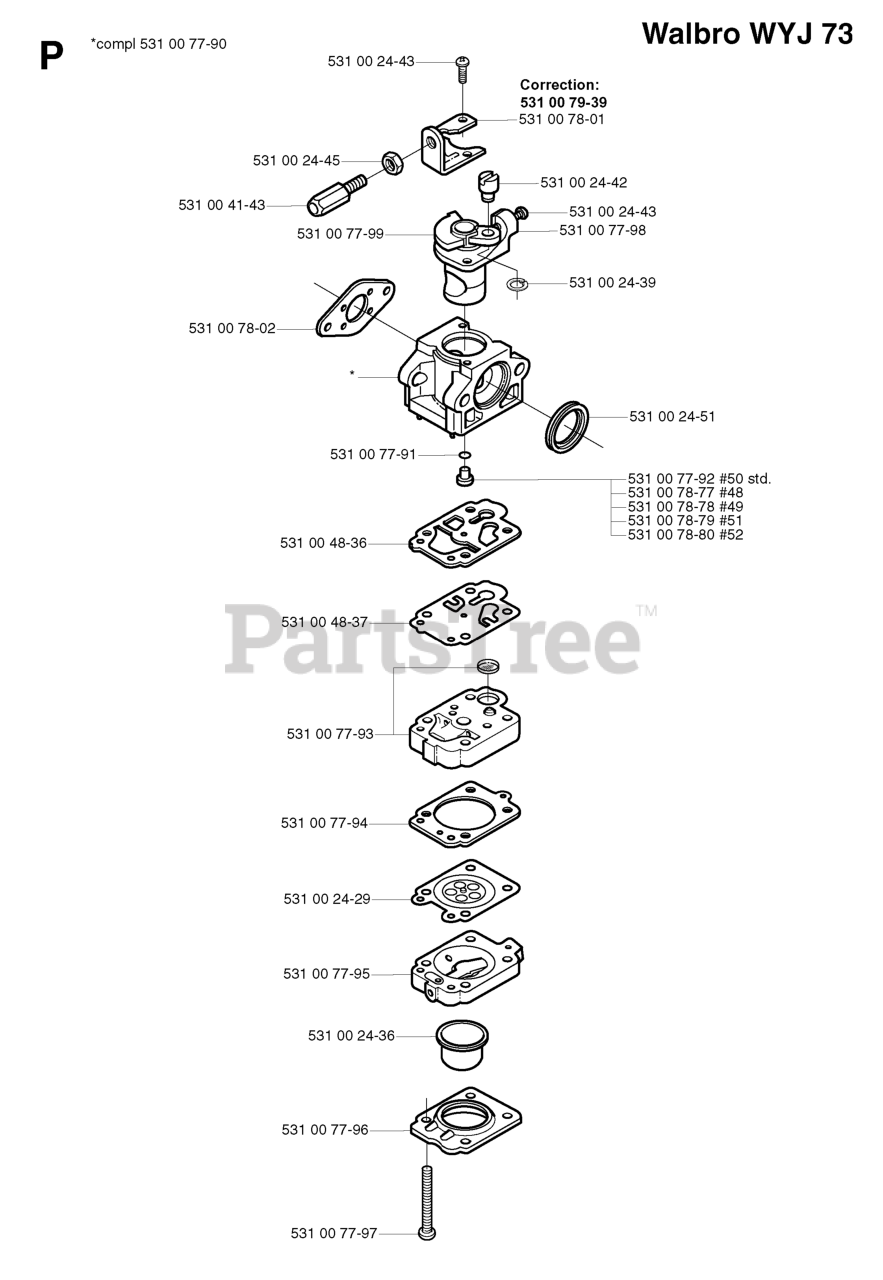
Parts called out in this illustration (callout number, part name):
2	KEY 1/4 X 2.5
7	HUB.ASM.WHEEL.REAR.23"TEX
9	HUB BOLT
15	WASHER
17	SPRING.BRAKE.HG3000/3500
26	SPRING.RETURN.CRUISE
33	E RING HYT
35	ROD.BRAKE.PARKING.GT.H
42	PEDAL COVER T
48	BOLT.3/8-16X1.50
50	IDLER.FLAT.910.OFFSET
51	NUT LOCK FLG 3/8-16 UNC
52	IDLER.V-GROOVE.910.OFFSET
56	V-BELT.GROUND.DRIVE.
64	SHAFT.ASM.PEDAL.BRK.CNTR
70	RP CONSOLE.ASM.PCH.W/TB
73	BOLT HEX FLGHD 5/16-18X3 GR. 5
74	SCREW.HI-LO.CONSOLE
80	STRAP.TORQUE.YT.G700
92	BOLT
99	SPRING.BYPASS.YT.G700
114	NUT.71038.31-18.HEX.NYLOCK
116	NUT LOCK HEX FLANGE 5/16-18
121	BRACKET STRAP TORQUE
125	SCREW
145	WASHER.AXLE.FLANGE.HG-3000
153	RETAINER M
159	COTTER PIN
160	RETAINER CLIP
161	SPRING, RETURN LT
163	ROD PEDAL CONTROL
166	NUT.PUSH.625
167	LATCH.BRAKE.SPRING
184	HANDLE.PARKG.BRK.HUSQ X667
186	SPACER.RETAINER
187	WASHER 12/32X2X10GA
188	RP.LINK.CLUTCH.GROUND.DRIVE
189	BELLCRANK.GROUND.DRIVE.TRAPPED
190	KEEPER BELLCRANK ROUND DRIVE
196	SCREW 3/8-16X1
197	BRKT.ANIT-ROTATION.CLUTCH
203	WASHER
206	BRKT.MOUNT.LATCH.CRUIS
207	LATCH.CONTROL.CRUISE
208	GEAR.SECTOR.CONTROL.CR
209	ROD.CONTROL.CRUISE.GT.
210	ROCKER.ASM.PEDAL.CONTR
211	BEARING.NYLON
213	KNOB.CONTROL.CRUSIE.HU
214	PEDAL.FORWARD.HUSQVARNA.DEALER
215	PEDAL.REVERSE.TEX.GT.4
220	REFLECTOR.RH.TEX GT
221	RETAINER.SPRING.CLIP.H
222	WASHER 21/32 X 1-1/4 X 10 GA.
284	NUT.U-CHNL.1/4-20.550DP.350PNL
285	SCREW.PHD.1/4-20.BOX DRVE
286	BOLT.5/16-18X2.5
306	PIN COTTER
